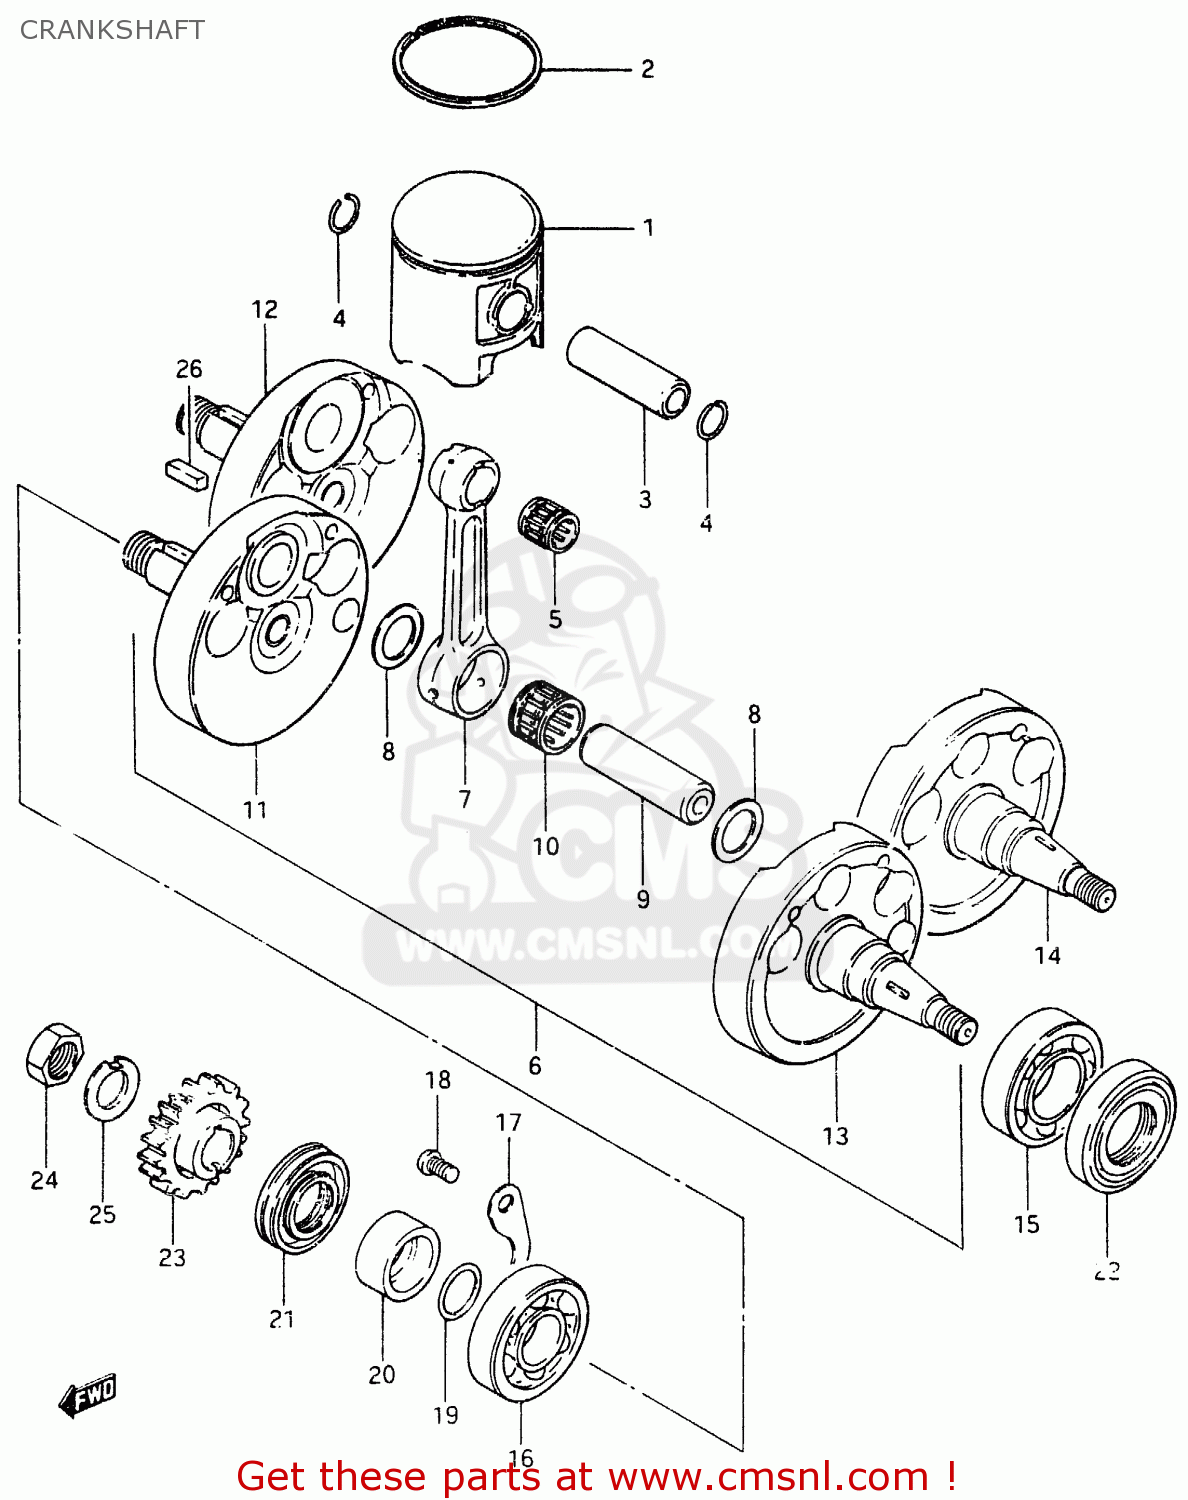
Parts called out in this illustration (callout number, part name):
1	PISTON (86.00MM)
2	RING,PISTON
3	PIN,PISTON (18MM)
4	CIRCLIP,PISTON PIN
5	BEARING(18X23X22)
6	CRANKSHAFT ASSEMBLY
7	ROD,CONNECTING
8	WASHER (25X30X1.5)
9	PIN,CRANK
10	ROLLER BEARING (25X31X2
11	CRANKSHAFT,RIGHT
12	CRANKSHAFT,RIGHT
13	CRANKSHAFT,LEFT
14	CRANKSHAFT,LEFT
15	BEARING,LEFT
16	BEARING
17	PLATE,CRANKSHAFT OIL S
18	SCREW
19	O-RING (D:3 ID:23.5)
20	SPACER,PRIMARY DRIVE GEAR
21	SEAL,OIL(37X62X9)
22	SEAL,OIL(19.6X37X8)
23	GEAR,PRIMARY DRIVE
24	NUT
25	WASHER
26	KEY
